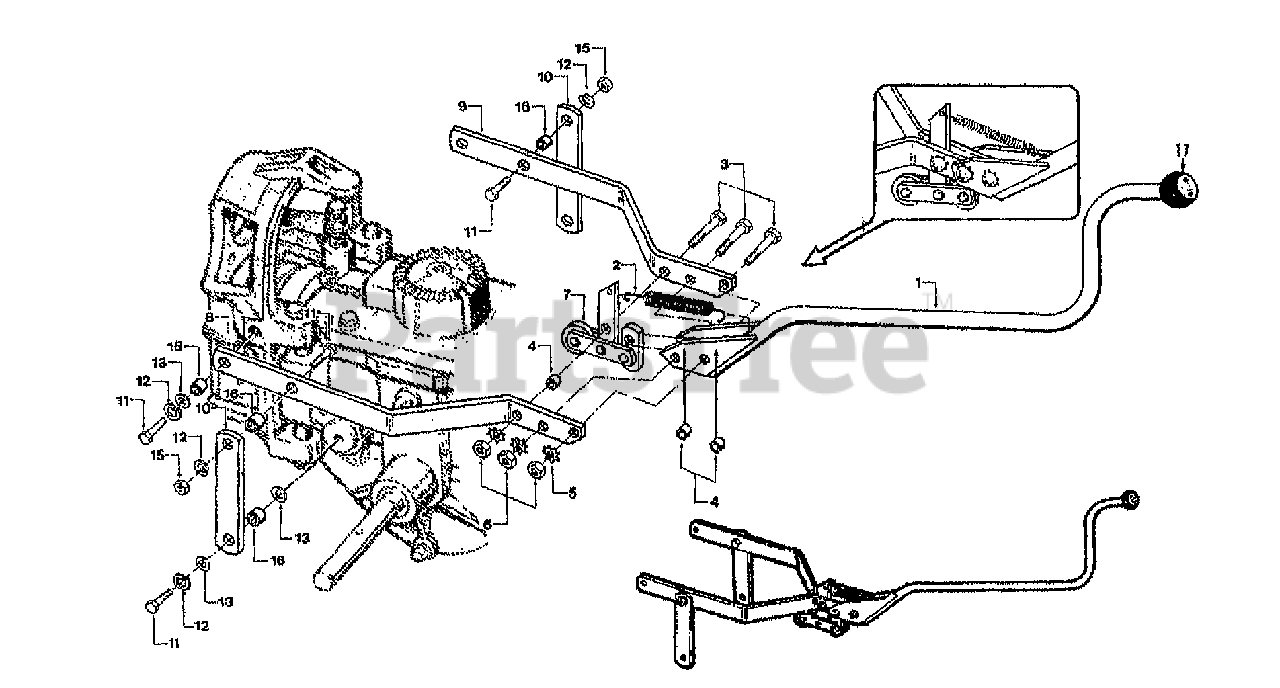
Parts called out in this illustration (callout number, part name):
1	ASSM-FOR/REV LEVER (INCL. KNOB W/DECAL)
2	SPRING-.436 X 3.25
3	SCR-HH 5/16-18X1.5 G5 ZP
4	BUSHING-.5X.316X.375 PM
5	WASHER-LK .312 EXT TOOTH
6	NUT-HEX 5/16-18 ZP
7	ASSM-ROLLER PAINT
8	YOKE-LH RED
9	YOKE-RH RED
10	YOKE-RED 2164
11	SCR-HH 3/8-16X1.0 G5 ZP
12	WASHER-LK .375 @ DEPL
13	WASHER-FLAT 3/8 SAE
14	THIS REF. NO. NOT USED
15	NUT-HEX 3/8-16 ZP
16	BUSHING-.5X.375X.3 (.300")
17	KNOB - NOT AVAIL. SEPARATELY. SEE REF. NO. 1
